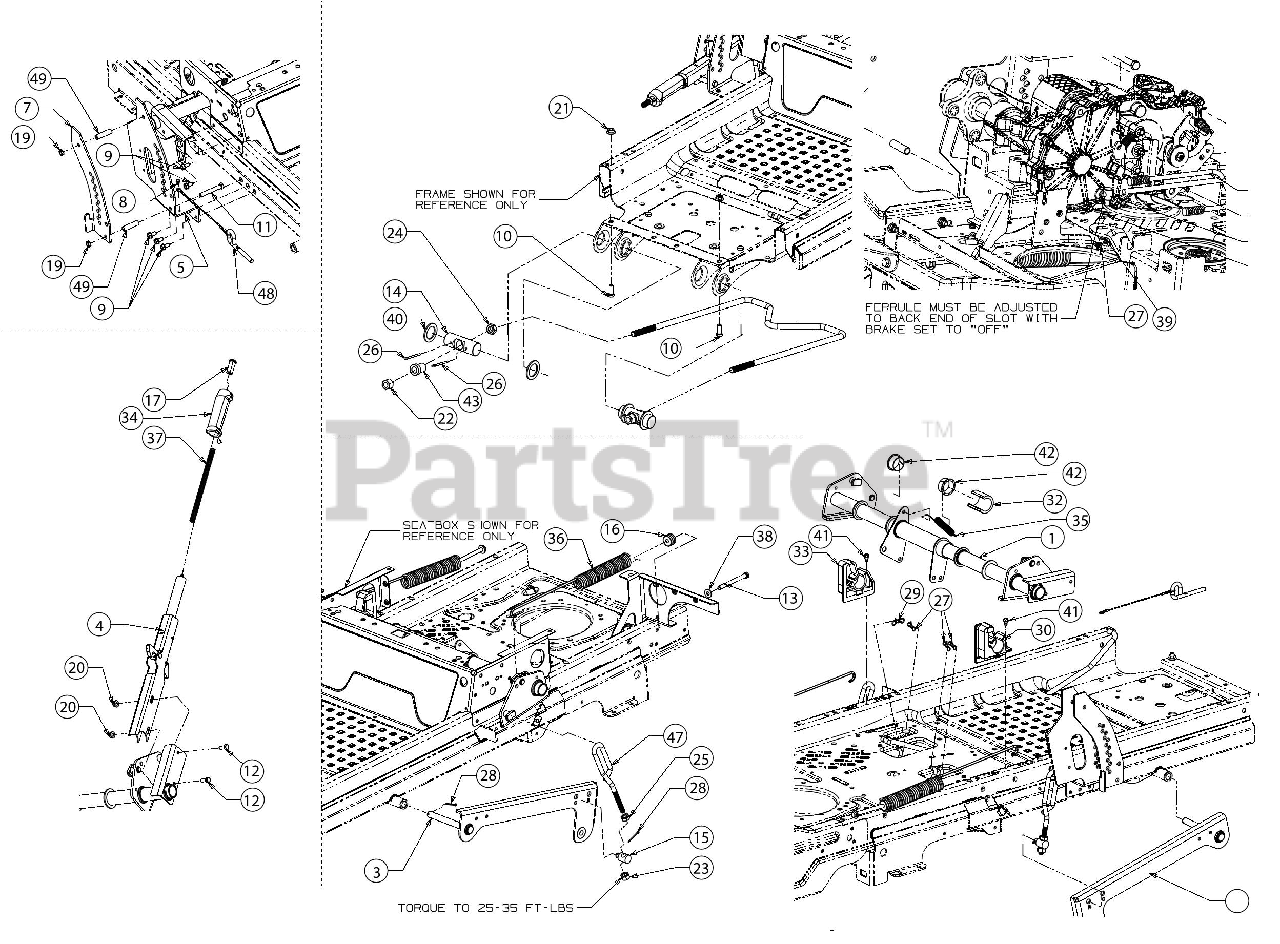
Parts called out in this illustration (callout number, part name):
1	DECK LIFT SHAFT ASSEMBLY
4	LATCH HANDLE ASSEMBLY
5	LIFT BRACKET ASSEMBLY
6	BRAKE ROD ASSEMBLY
7	OUTER INDEX BRACKET
8	HEX SCREW AB-TAP #10-16 X 0.500
9	SCREW 5/16-18 X .750
10	SCREW 3/8-16 X 1 GR5
11	HEX SCREW-3/8-16X2.5 GR5
12	SCREW 5/16-18 X .75 GR5
13	SCREW 3/8-16X4.25 GR5
15	LIFT LINK FERRULE
16	SPRING INSERT
17	LIFT HANDLE BUTTON
18	FERRULE 3/8-24 X .375
19	JAM LOCK NUT
20	FLANGE LOCK NUT 5/16-18
21	FLANGE LOCK NUT
23	HEX NUT NYLOK 1/2-13
24	HEX NUT
25	HEX NUT
26	COTTER PIN
27	BOW TIE COTTER PIN 1/4-5/16
28	COTTER PIN
29	BOW TIE COTTER PIN
30	LOCTITE
31	DECK LIFT BRACKET
32	SPACER-1.375 SHAFT
33	DECK LIFT BRACKET (LH)
34	LIFT HANDLE GRIP
35	EXTENSION SPRING .63 X 4.95
36	EXTENSION SPRING
37	COMPRESSION SPRING
38	FLAT WASHER .385X.870X.090
39	WASHER THRUST .375X.70X.030
40	FLAT WASHER
41	SHOULDER SCREW 1/4-20X.50 19PSH"
42	FLANGE BEARING
43	FLANGE BEARING
45	DISENGAGEMENT BRAKE ROD
46	DECK FRONT HANGER ROD
47	LIFT ADJUSTMENT LINK
